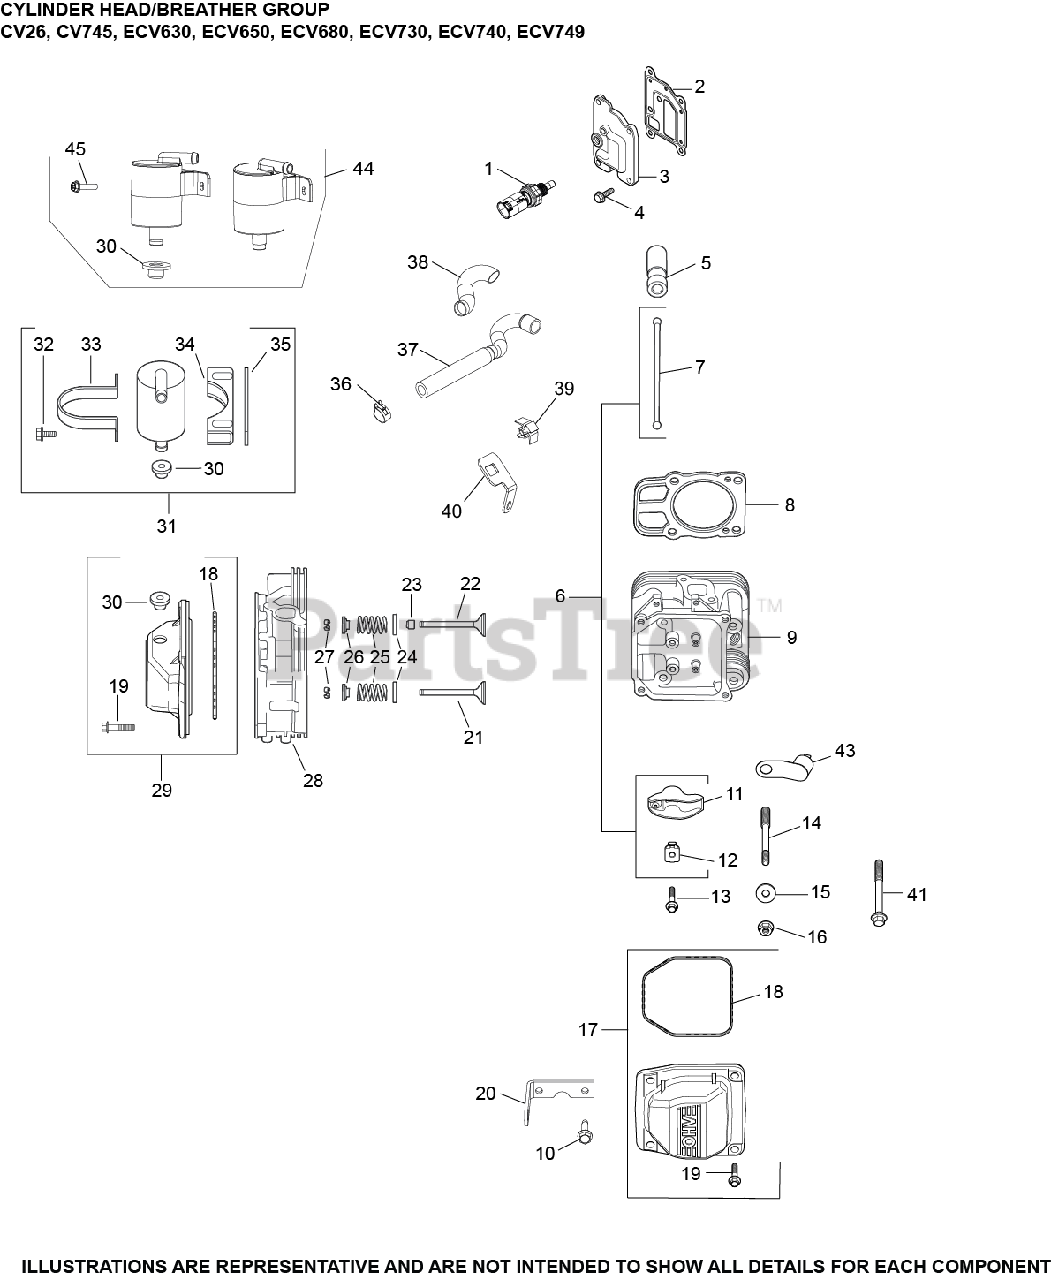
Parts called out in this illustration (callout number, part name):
1	SENSOR, TEMPERATURE
2	GASKET, BREATHER
3	KIT, BREATHER COVER
4	SCREW, THREAD FORMING
5	LIFTER, VALVE HYDRAULIC - (#2535111S)
6	KIT, VALVE TRAIN
7	ROD, PUSH
8	KIT, CYLINDER HEAD GASKET
9	KIT, CYLINDER HEAD #2
10	SCREW, THREAD FORMING
11	ARM, ROCKER
12	PIVOT, ROCKER ARM
13	SCREW, FLG M6X1.0X34
14	STUD, M8X1.25
15	WASHER, FLAT 8.6 MM
16	NUT, FLG M8X1.25
17	KIT, VALVE COVER-PLAIN
18	O-RING (YELLOW), VALVE COVER
19	SCREW, FLG M6X1.0X30
20	STRAP, LIFT
21	VALVE, EXHAUST
21	VALVE, EXHAUST (.25)
22	VALVE, INTAKE (STD)
22	VALVE, INTAKE (.25)
23	SEAL, VALVE BAND
24	RETAINER, SPRING
25	SPRING, VALVE
26	CAP, VALVE SPRING
27	KIT, RETAINER
28	KIT, CYLINDER HEAD #1
29	KIT, VALVE COVER
30	GROMMET, RUBBER
32	SCREW, THREAD FORMING
36	CLAMP, HOSE-USE 25 237 32-S
37	HOSE, BREATHER
38	SLEEVE, ANTI ABRASION 4.4 O.L.-USE 25 431 12-S
39	CLIP, O2 SENSOR
40	BRACKET, OXYGEN SENSOR
45	SCREW, HEX FLANGE HI-LO
